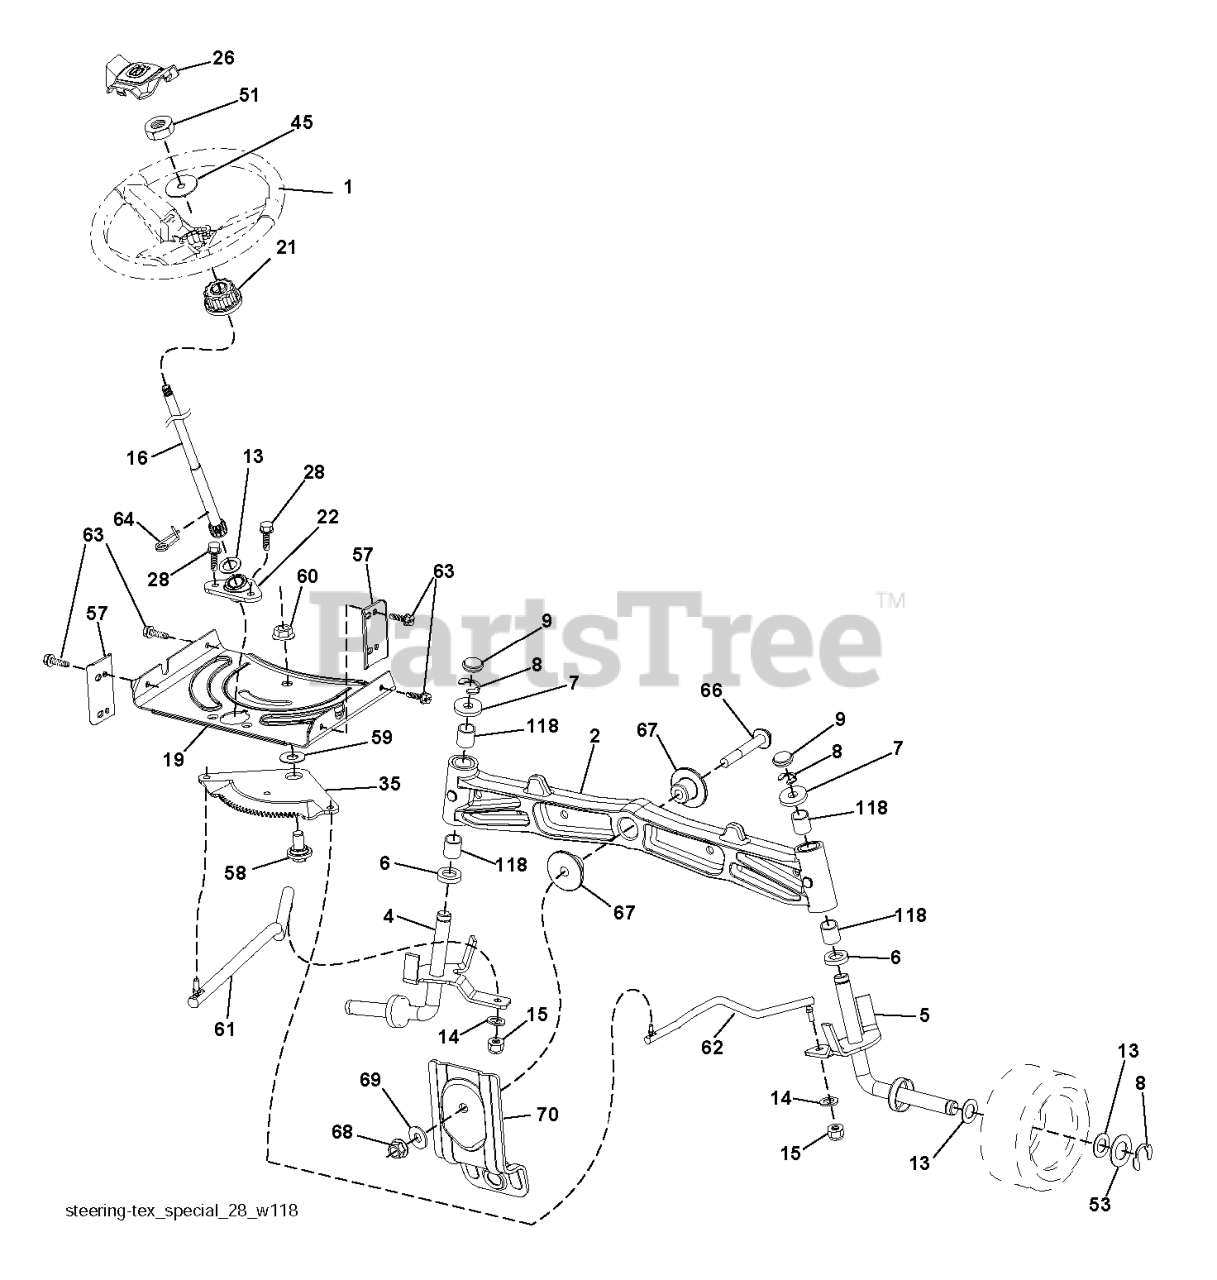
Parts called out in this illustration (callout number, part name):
1	RP WHEEL.STEER.HUSQ.PREM.OVMLD
2	AXLE.SVC.ASM CAST IRON.TEX
4	SPINDLE.WELDED.LH.15"TEX
5	SPINDLE.WELDED.RH.15"T
6	THRUST WASHER
9	CAP.SPINDLE.BLACK
14	WASHER, LOCK 3/8
15	NUT CROWNLOCK 3/8-24
16	SHAFT.STEER.STEALTH.DD
19	PLATE.STEER.DDL.NLT/NG
21	ADAPTER, WHEEL STNG..
22	BUSHING.ASM.STEERING.A
26	RP INSERT.CAP.WHL.STRG.HUSQ.
28	SCREW, 3/8-16X3/4
35	GEAR.SECTOR.PLATE.DDL.
45	WASHER 9/16"ID, 2 3/8"OD
51	NUT.HEX.1/2-20
53	WASHER.HARDENED
57	BRACKET.UPSTOP.TEX
58	BOLT.SHOULDER.SECTOR.P
59	WASHER.THURST.SECTOR.S
60	NUT FLANGE LOCK 5/8-11
61	DRAGLINK.LH.BALLSTUD.D
62	DRAGLINK.RH.BALLSTUD.D
63	SCREW
64	RETAINER.CLIP.SPRING.S
66	BOLT HEX FGHD 7/16-14 X 3 SERR
67	BUSHING.PM.FRONT AXLE
68	NUT.LOCK.FLANGE.7/16
69	WASHER.1.5X.505X.118
70	BRKT.DECK.SUSPENSION.F
118	BUSHING, AXLE CAST
